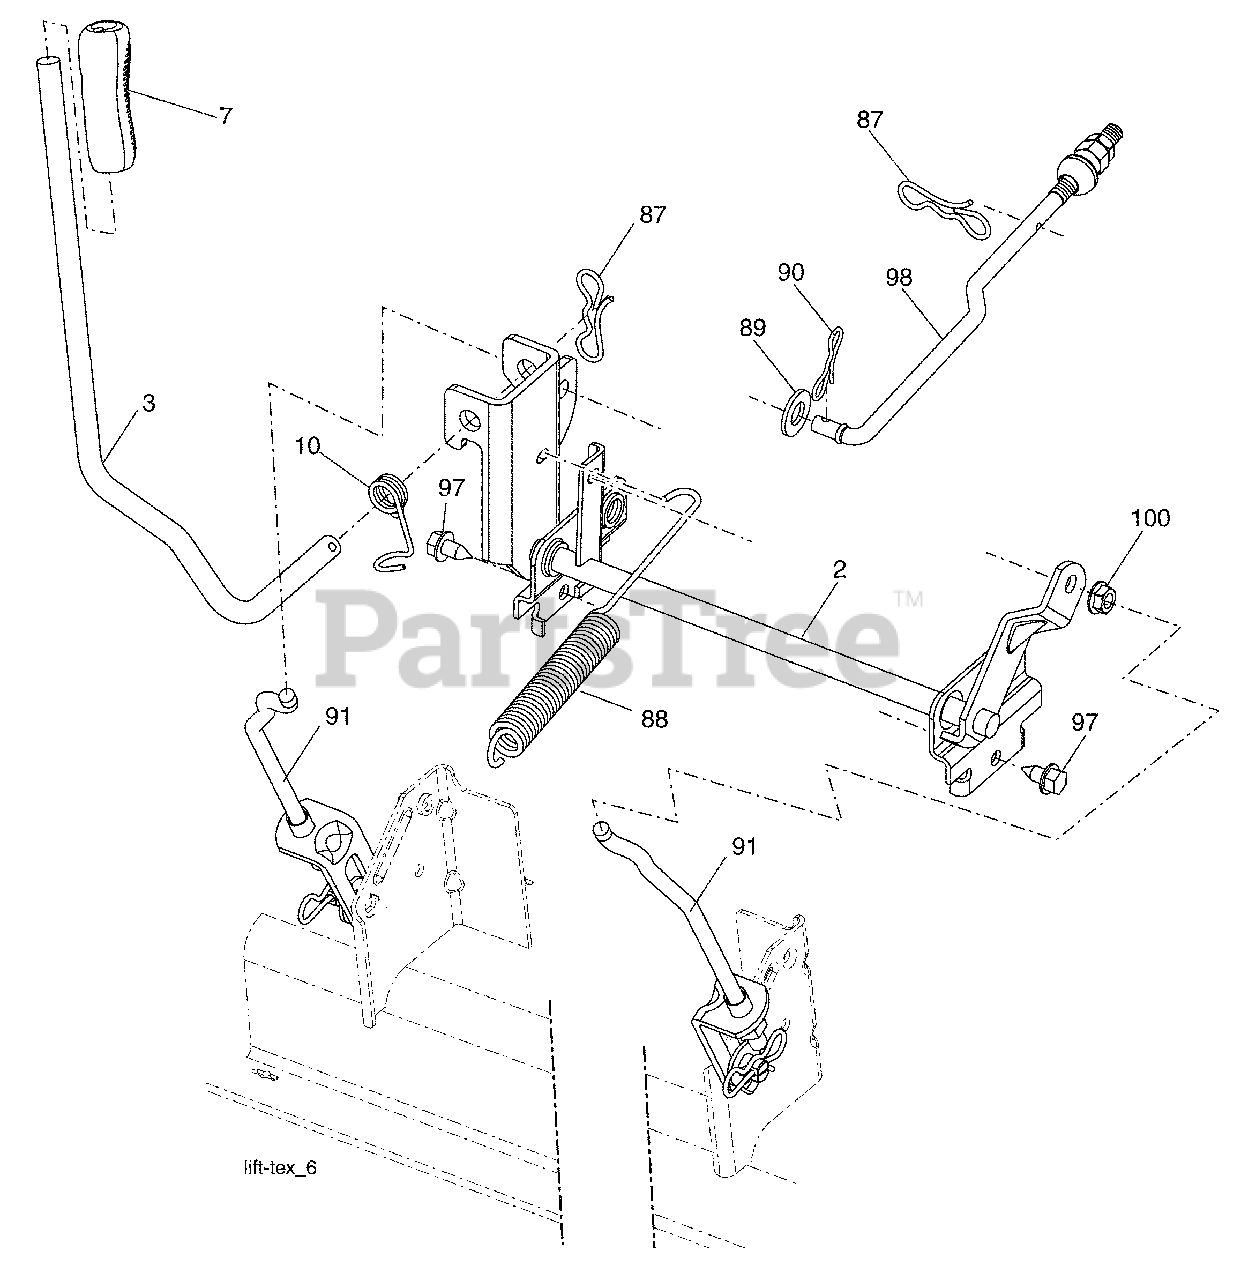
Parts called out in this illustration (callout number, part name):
2	Shaft Asm., Lift
3	Lever Asm., Lift RH
7	Grip, Lever
10	Spring Torsion
87	Pin Cotter 7/16 Bow Tie Lock
88	Spring Lift Assist
89	Washer Clear Zinc
90	Pin Cotter 5/16 Bow Tie Lock
91	Link Lift Susp Mower Rear
97	Screw 3/8-16 x .75 Smgml Tap/R.Z
98	Link Lift Susp. Front Mower
100	Nut Center Lock 3/8-16 UNC
